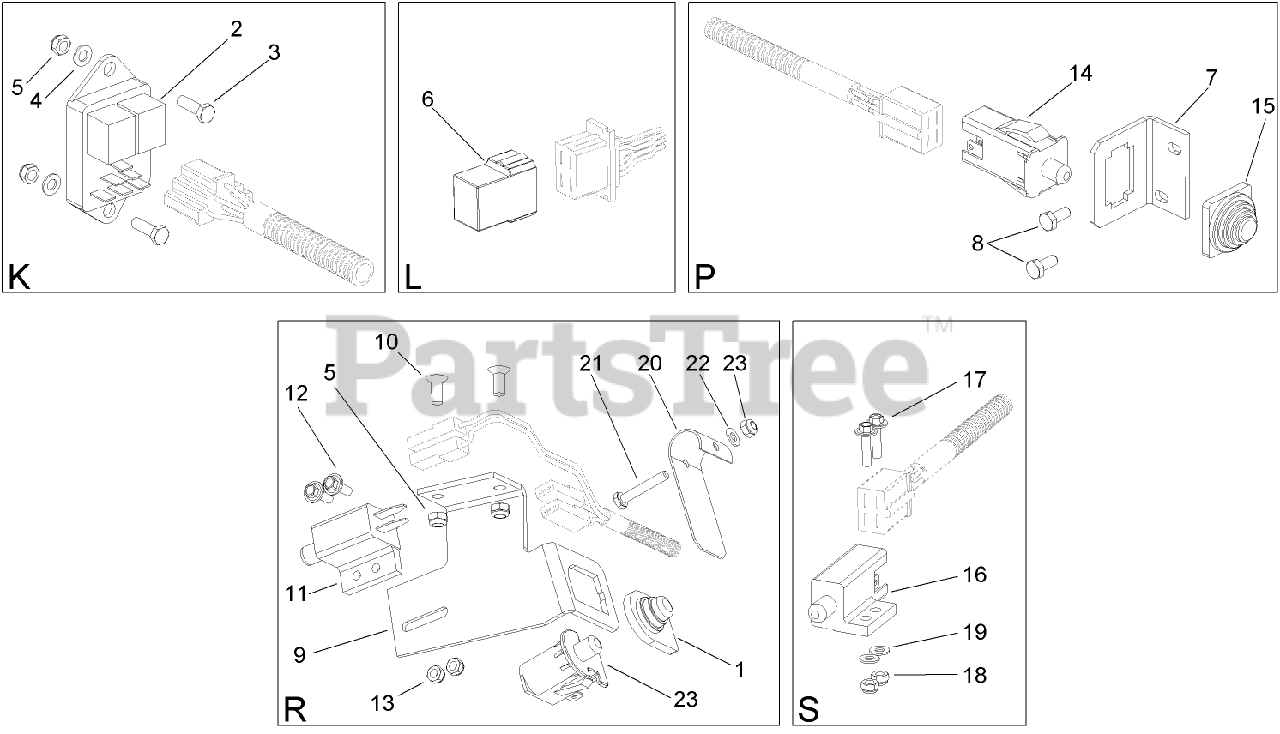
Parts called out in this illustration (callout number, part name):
1	COVER-PROTECTIVE
2	MODULE-CLUTCH
3	SCREW-HH
4	WASHER
5	NUT-LOCK
6	CIRCUIT-MEMORY
7	Holder-Switch
9	Holder-Switch
11	SWITCH-POLE, SINGLE
13	NUT-HEX
14	SWITCH-DELTA
15	Cover-Switch
16	Switch-Delta
18	NUT-LOCK
19	WASHER
21	SCREW-HEX
22	Washer
23	SWITCH-DELTA
